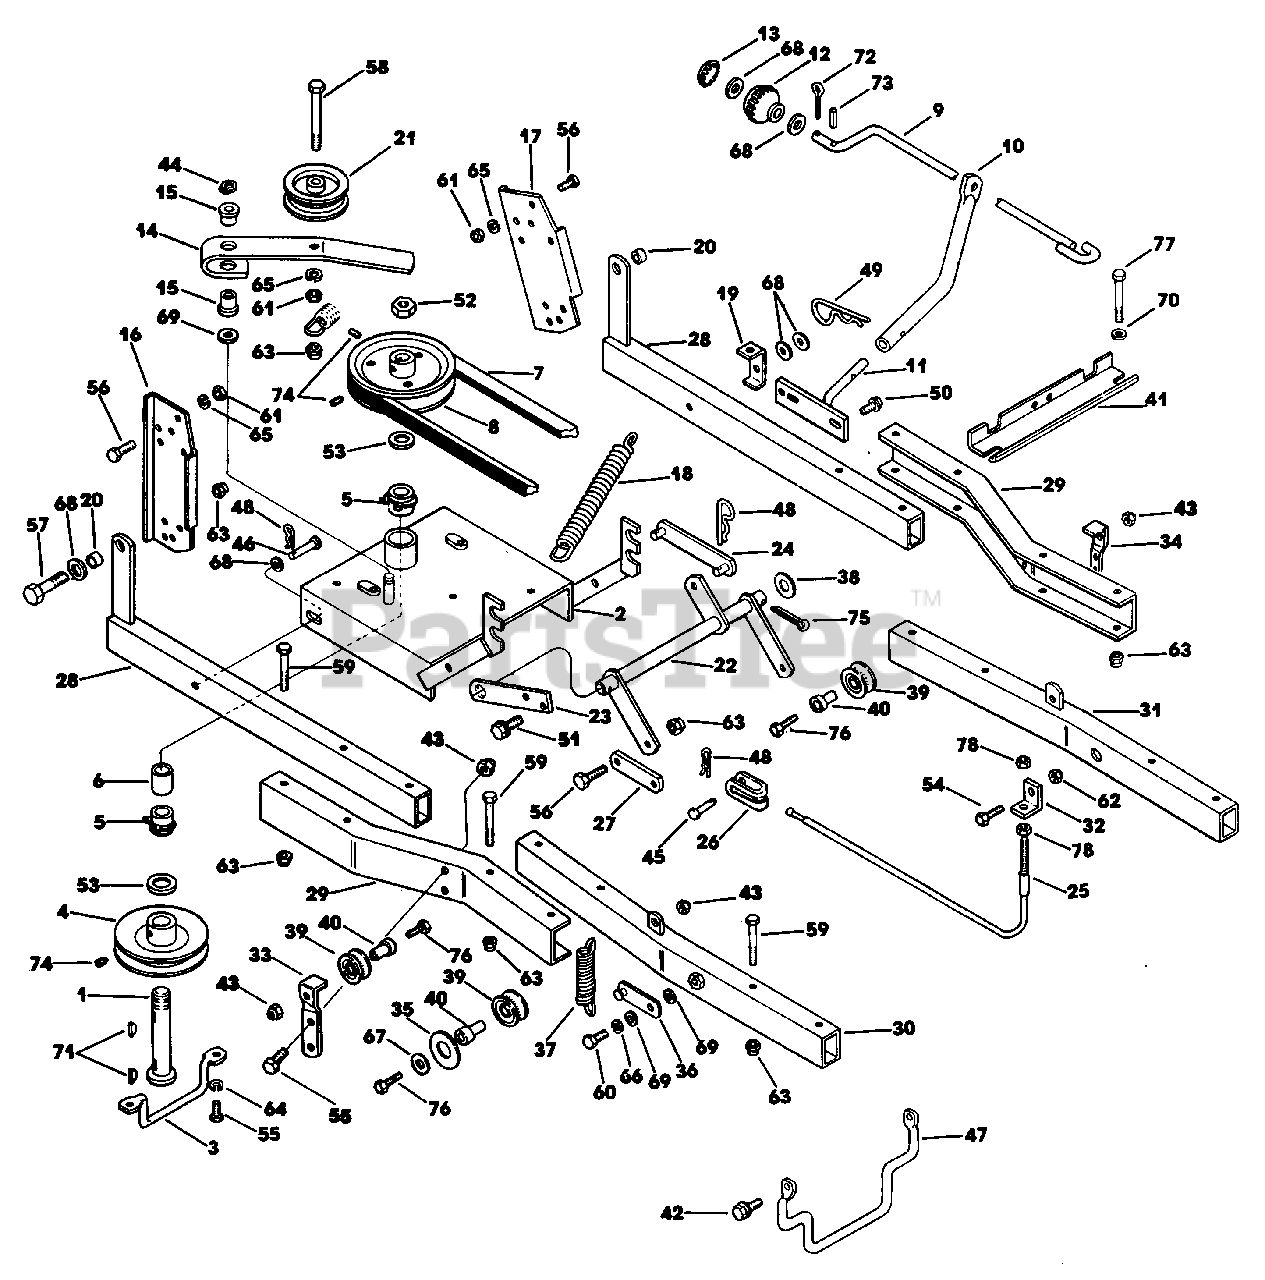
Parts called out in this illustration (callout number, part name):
1	Shaft Assembly
2	Pulley Support Assembly
3	Belt Guard
4	Pulley
5	Bearing w/Snap Ring
6	Spacer
7	V-Belt (Primary)
8	Pulley
9	Chute Control Assembly
10	Tube-Chute Control Support
11	Support Assembly-Chute Control
12	Knob
13	Plug Button & Decal Assembly
14	Idler Arm Assembly w/Bushing
15	Bushing
16	Attachment Mounting Bracket-R.H.
17	Attachment Mounting Bracket-L.H.
18	Spring Idler
19	Spring Anchor
20	Spacer
21	Idler Pulley
22	Bellcrank Crank Assembly
23	Lift Support Arm
24	Lift Link Assembly
25	Lift Cable
26	Lift Clevis
27	Bar-Cable Connector
28	Rear Frame Assembly
29	Frame Connecting Channel
30	Front Frame Assembly
31	Front Frame Assembly L.H.
32	Bracket, Cable Adjustment
33	Plate-Roller Mounting-R.H.
34	Plate-Roller Mounting-L.H.
35	Washer
36	Spring Adjustment Arm Assembly
37	Spring-Assist
38	Washer
39	Roller-Cable
40	Spacer-Roller
41	Frame Stop
42	Thread Forming Screw, Hex Hd. 1/4-20 x 1/2
43	Nut, Hex Cone Lock 5/16-18 Plated
44	Snap Ring
45	Clevis Pin
46	Clevis Pin
47	Belt Guide (Engine)
48	Spring Clip
49	Spring Clip
50	Thread Forming Screw, Hex Hd. 5/16-18 x 3/4
51	Thread Forming Screw, Hex Hd. 5/16-18 x 1"
52	Nut, Hex Center Lock 5/8-18
53	Thrust Washer
54	Cap Screw, Hex Hd. 1/4-20 x 3/4 Plated, Grade 5
55	Cap Screw, Hex Hd. 5/16-18 x 3/4 Plated, Grade 5
56	Cap Screw, Hex Hd. 3/8-16 x 1" Plated, Grade 5
57	Cap Screw, Hex Hd. 3/8-16 x 1-1/2" Plated, Grade 5
58	Cap Screw, Hex Hd. 3/8-16 x 2-1/4" Plated, Grade 5
59	Cap Screw, Hex Hd. 3/8-16 x 2-3/4" Plated, Grade 5
60	Cap Screw, Hex Hd. 1/2-13 x 1" Plated, Grade 5
61	Nut, Hex 3/8-16 Plated
62	Nut, Hex Cone Lock 1/4-20 Plated
63	Nut, Hex Cone Lock 3/8-16 Plated
64	Washer, Spring Lock 5/16 Plated
65	Washer, Spring Lock 3/8 Plated
66	Washer, Spring Lock 1/2 Plated
67	Washer Flat 5/16 Plated
68	Washer, Flat SAE 3/8 Plated
69	Washer, Flat SAE 1/2 Plated
70	Washer, Flat 3/8 Plated
71	Key, Woodruff 3/16 x 5/8 Grade 5
72	Pin, Cotter 1/8 x 3/4 Plated
73	Pin, Roll 1/8 x 3/4 Plated
74	Set Screw, Hex Socket Hd. Cup Pt. 5/16-18 x 5/16 Grade 5
75	Pin, Cotter 5/32 x 1-1/4" Plated
76	Cap Screw, Hex Hd. 5/16-18 x 1-1/2" Plated, Grade 5
77	Cap Screw, Hex Hd. 3/8-16 x 3" Plated, Grade 5
78	Nut, Hex 5/16-18 Plated
